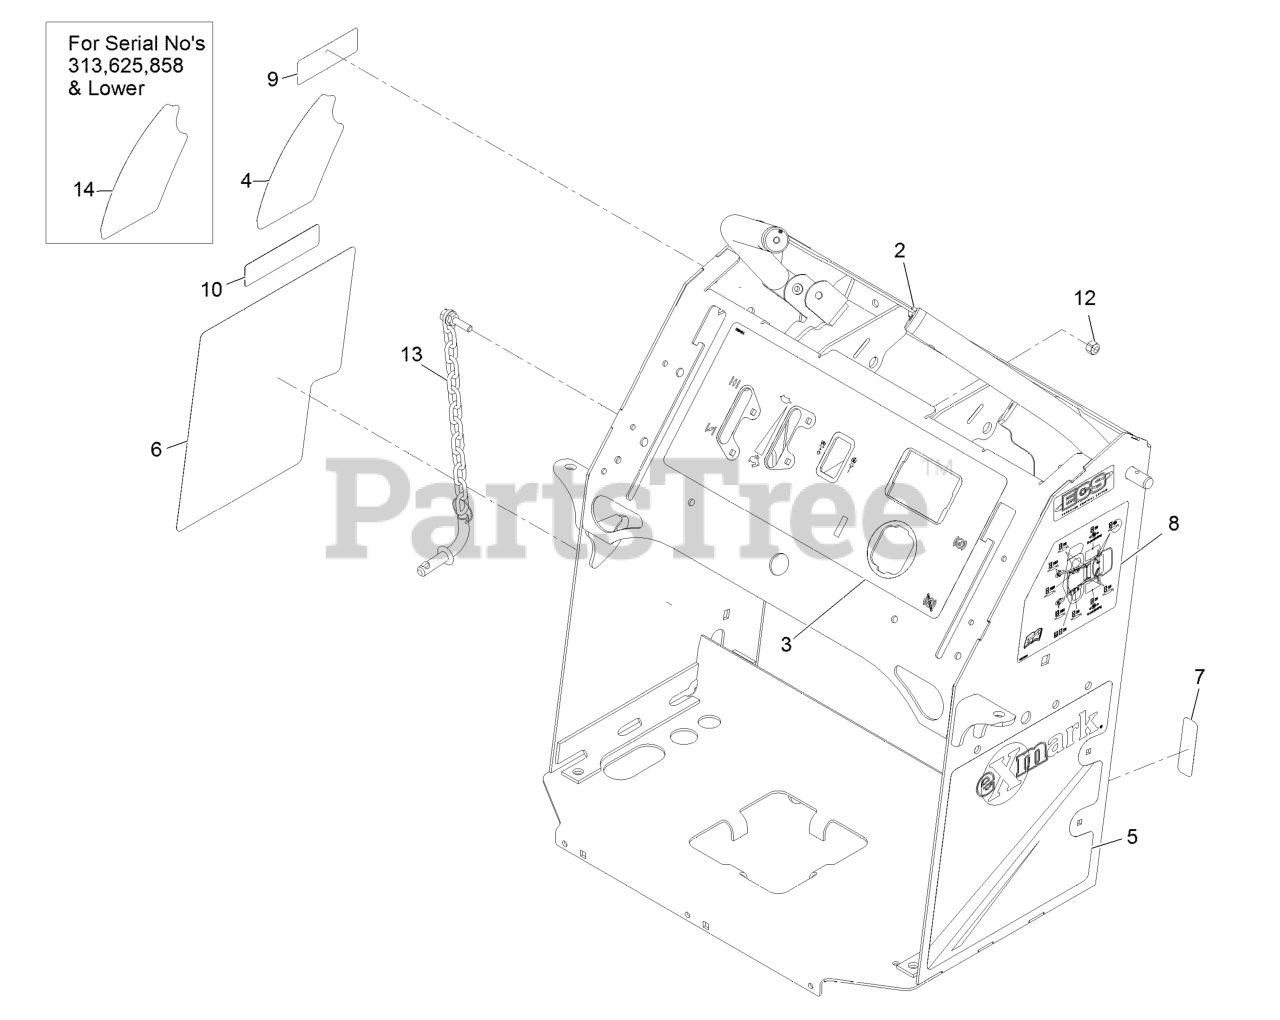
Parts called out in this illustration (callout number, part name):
3	DECAL-CONTROL PANEL ECS
4	DECAL-HEIGHT OF CUT
5	DECAL-LH PANEL
6	DECAL-RH PANEL
7	DECAL-FUSE
8	Decal-Service Aid
9	DECAL-ECS LOGO
10	DECAL-ARRESTER, SPARK
12	NUT-LOCK, NI
13	HOC PIN ASM
14	DECAL-HEIGHT OF CUT
